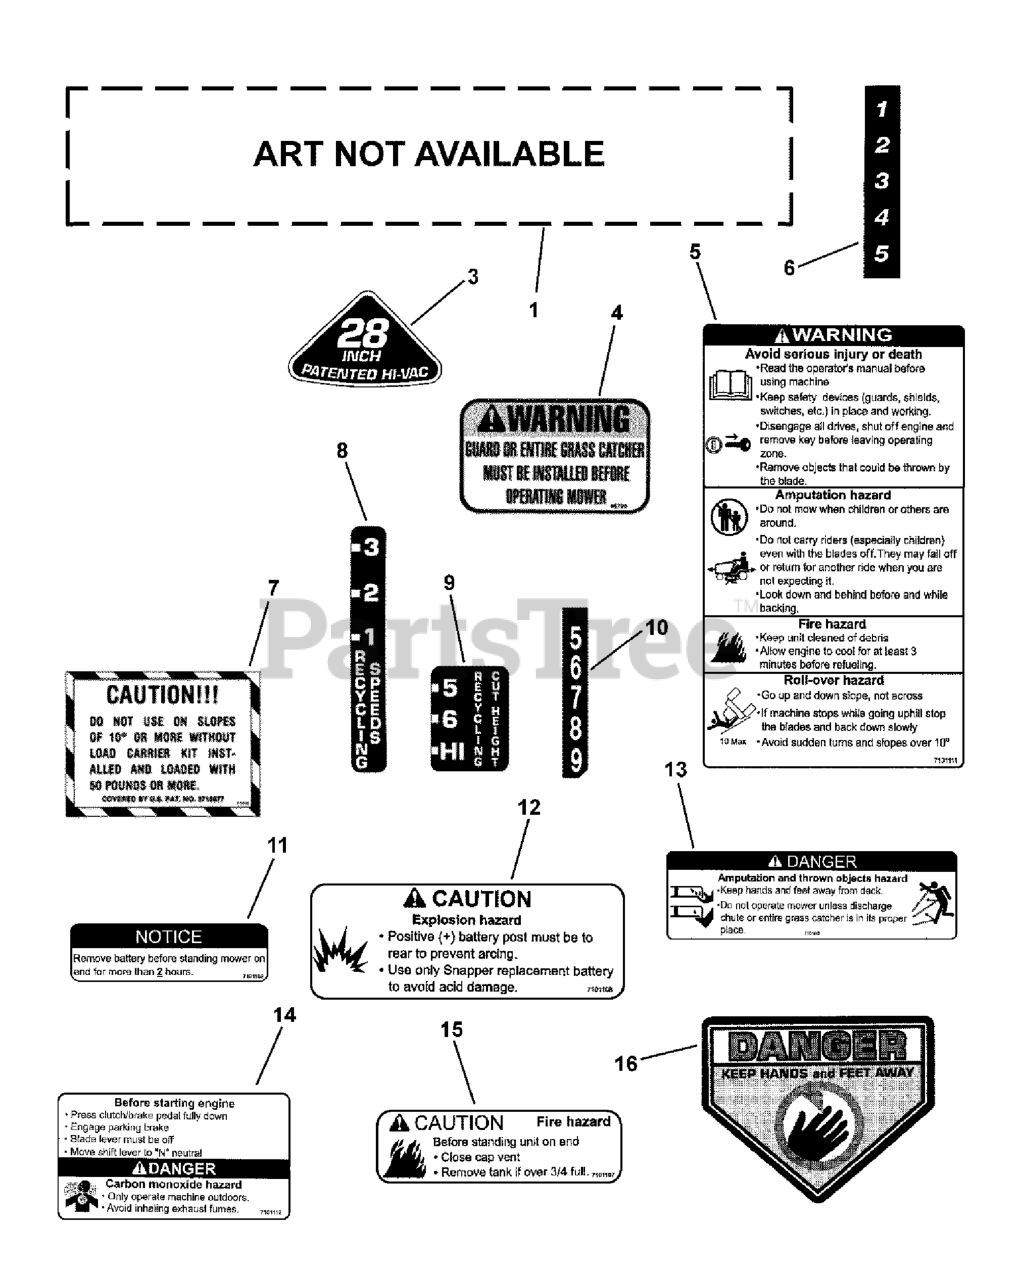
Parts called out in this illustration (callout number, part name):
1	DECAL, Craftsman
3	DECAL, 28 Inch (Hi-Vac)
4	DECAL, Chute/Deflector Warning
5	DECAL, Warning, Safety Panel
6	DECAL, Height of Cut
7	DECAL, Grass Catcher
8	DECAL, Recy Ground Speed
9	DECAL, Recy Height-Of-Cut
10	DECAL, Height-Of-Cut
11	DECAL, Remove Battery
12	DECAL, Caution, Battery
13	DECAL, Danger, Deck
14	DECAL, Danger, Safety Panel
15	DECAL, Caution, Fuel
16	DECAL, Danger, Cut Finger
